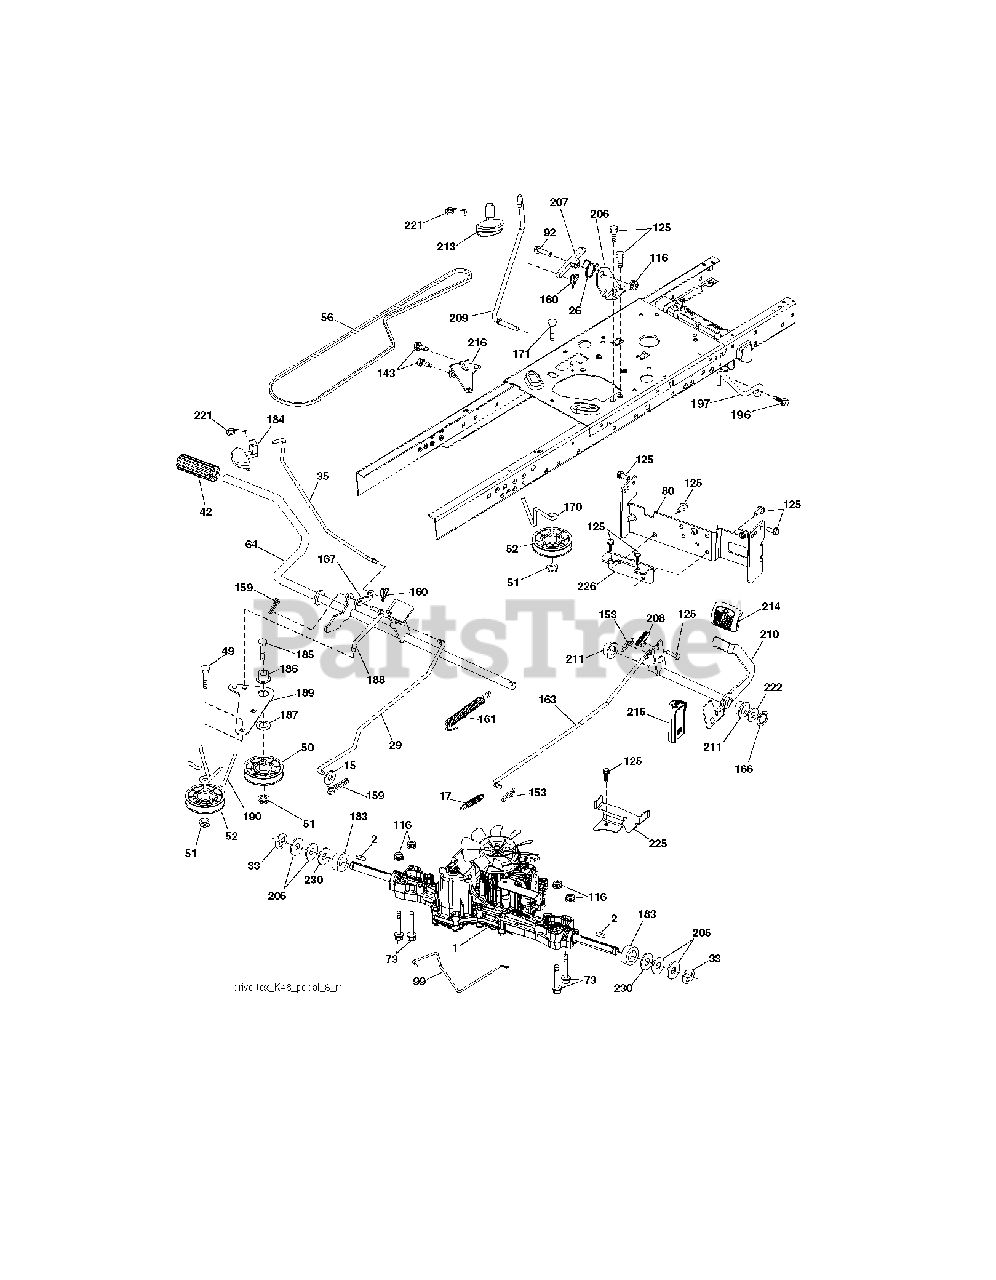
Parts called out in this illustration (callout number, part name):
2	SQUARE KEY
15	WASHER
17	SPRING.BRAKE.K46.GREEN
26	SPRING.RETURN.CRUISE
29	ROD.BRAKE.K46
35	ROD.BRAKE.PARKING.GT.H
42	PEDAL COVER T
50	IDLER.FLAT.910.OFFSET
51	NUT LOCK FLG 3/8-16 UNC
52	IDLER.V-GROOVE.910.OFFSET
56	V-BELT.MOWER.92.40.42/K46
64	SHAFT.ASM.PEDAL.BRK.CNTR
73	BOLT HEX 5/16-18 GR 5
80	STRAP TORQUE
92	BOLT
99	ROD.SPRING.BYPASS.K46.LT.Z
116	NUT LOCK HEX FLANGE 5/16-18
125	SCREW
143	SCREW LT
153	RETAINER M
159	COTTER PIN
160	RETAINER CLIP
161	SPRING, RETURN LT
163	ROD.CONTROL.PEDAL.K46
166	NUT.PUSH.625
167	LATCH.BRAKE.SPRING
170	KEEPER.V-IDLER.CENTER.
183	SPACER AXLE
184	HANDLE.PARKG.BRK.HUSQ X667
186	SPACER.RETAINER
187	WASHER 12/32X2X10GA
188	RP LINK.CLUTCH.GROUND.DRIVE
189	BELLCRANK.GROUND.DRIVE.TEX.
190	KEEPER.BELLCRANK.DRIVE
196	SCREW 3/8-16X1
197	LINK.CLUTCH.ANIT-ROTAT
206	BRKT.MOUNT.LATCH.CRUIS
207	LATCH.CONTROL.CRUISE
208	GEAR.SECTOR.CONTROL.CR
209	ROD.CONTROL.CRUISE.GT.
210	ROCKER.ASM.PEDAL.CONTR
211	BEARING.NYLON
213	KNOB.CONTROL.CRUSIE.HU
214	PEDAL.FORWARD.PAD.TEX
215	PEDAL.REVERSE.TEX.GT.4
216	BRACKET.PULLEY.IDLER.W/TEX
221	RETAINER.SPRING.CLIP.H
222	WASHER 21/32 X 1-1/4 X 10 GA.
225	KEEPER.BELT.TRANSAXLE.K46
226	BRACKET.MOUNT.TORQUE.K46.TLT
230	WASHER.HARDENED
